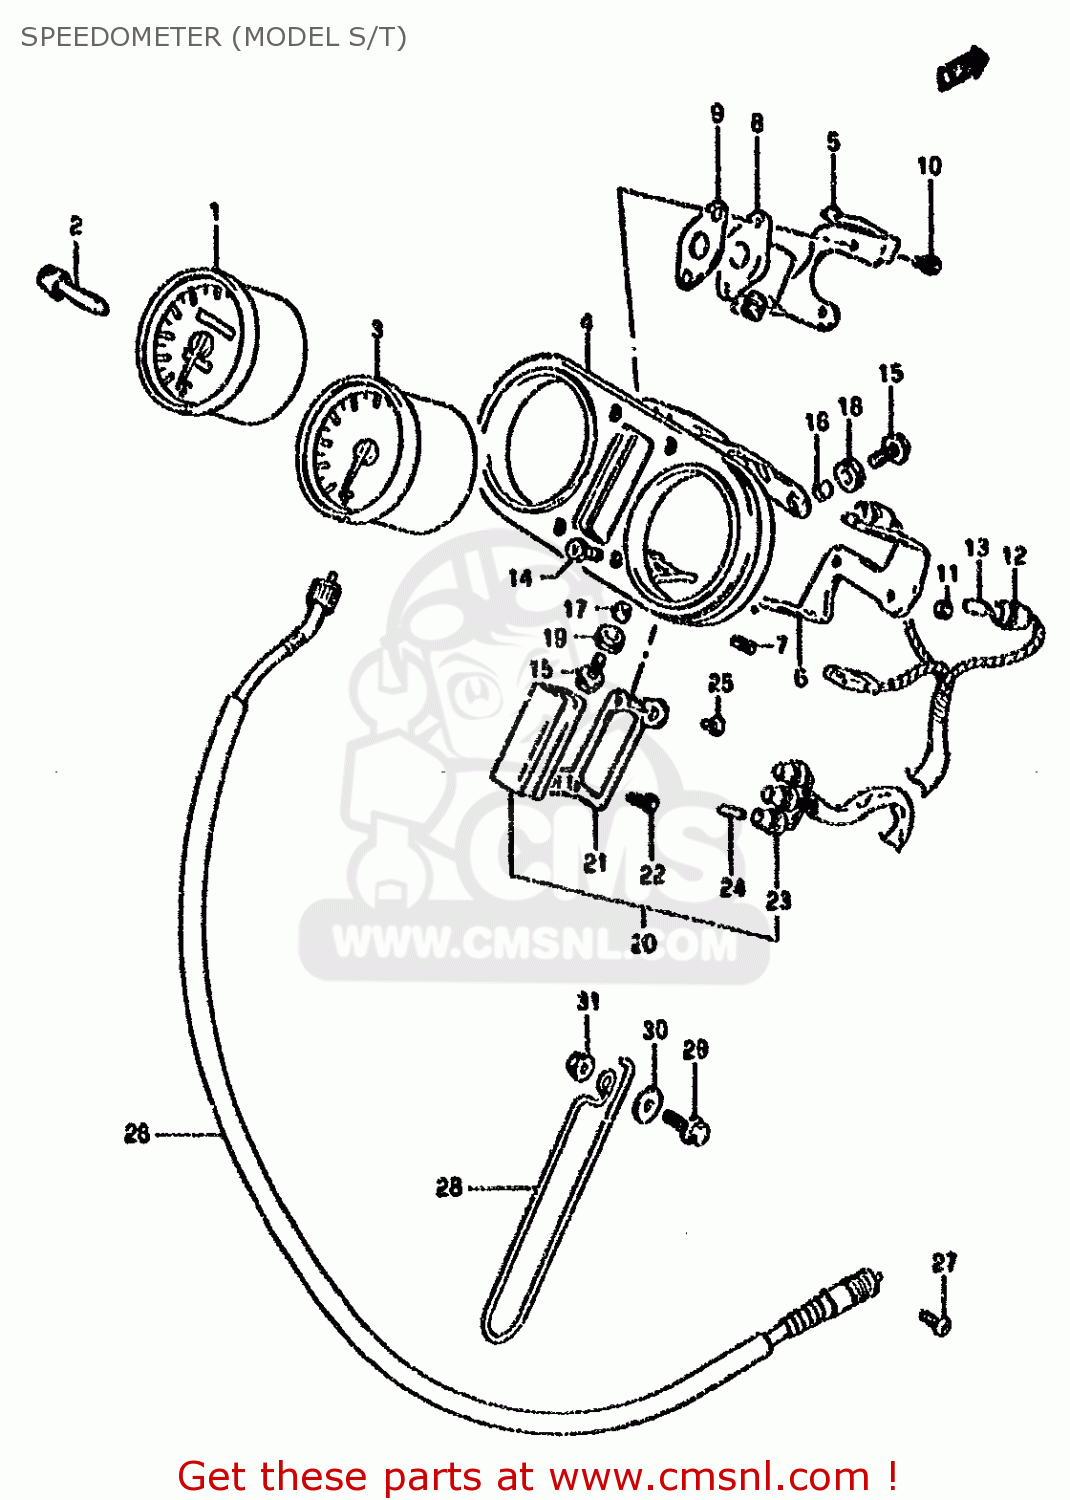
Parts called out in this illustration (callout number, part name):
1	SPEEDOMETER(KILO)
2	KNOB,TRIP
3	TACHOMETER
4	PANEL, METER
5	BRACKET,SPEEDOMETER
6	BRACKET, TACHOMETER
7	DAMPER
8	GEAR BOX
9	GASKET,METER GEAR BOX (NAS)
10	SCREW
11	NUT
12	SOCKET
13	BULB(12V3W,T6.5)
14	BOLT
15	BOLT 6X20
16	SPACER (6.4X9X10.5)
17	SPACER (6.1X8X9.5)
18	CUSHION
19	CUSHION
20	BOX ASSY, PILOT LAMP
21	BRACKET,PILOT BOX
22	SCREW, OUTER
23	SOCKET
24	BULB(13.5V,2W,A7427)
25	SCREW
26	CABLE ASSY,SPE
27	SCREW
28	GUIDE,METER CABLE NO.2
29	BOLT
30	WASHER(6.5X20X1.6)
31	NUT
32	WASHER(6.5X20X1.6)
33	NUT
